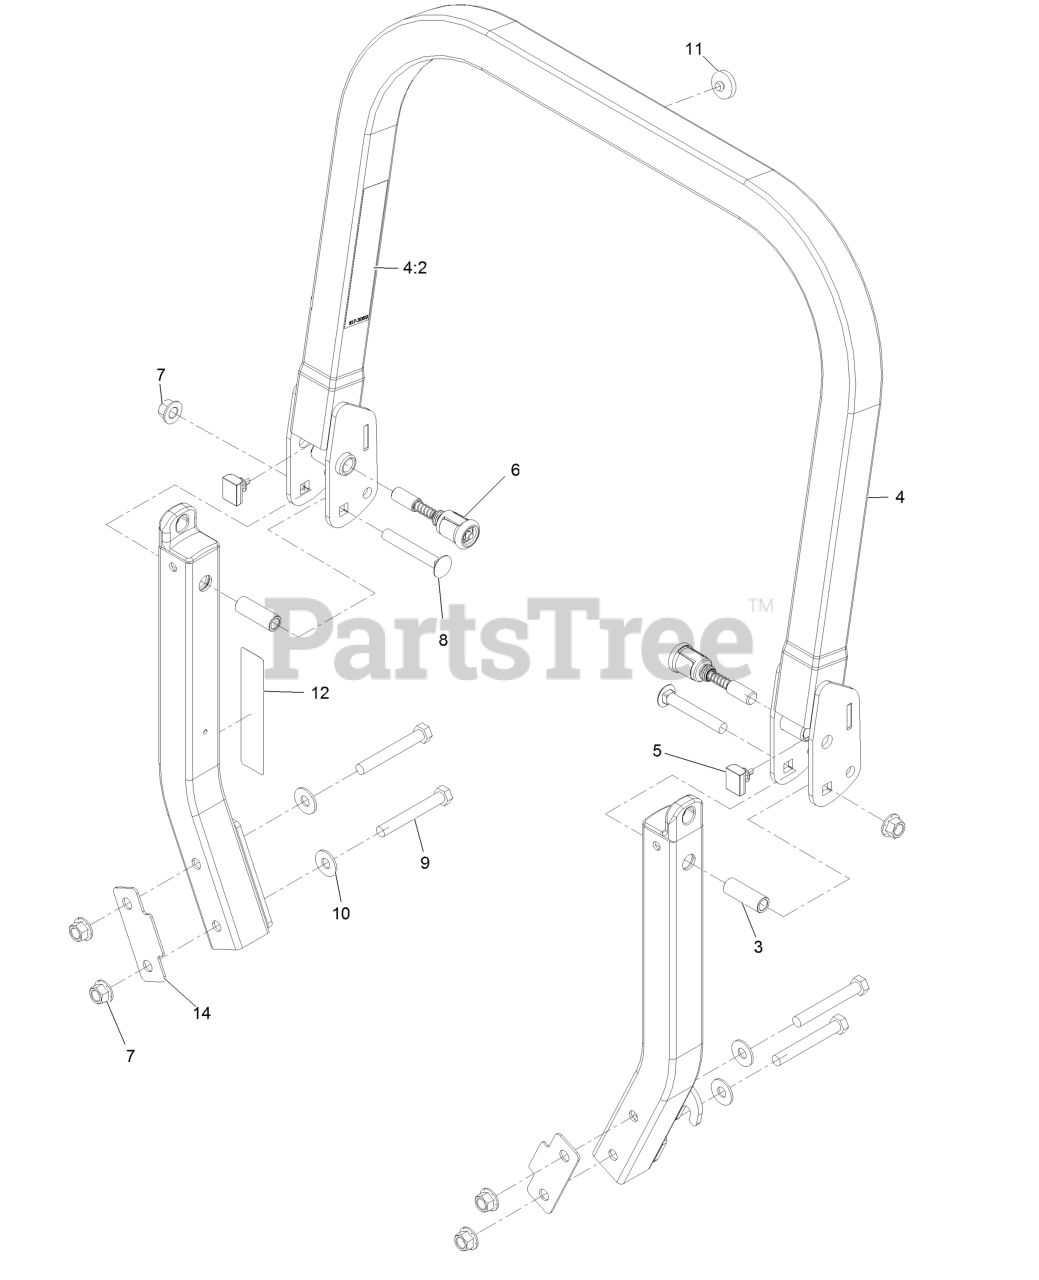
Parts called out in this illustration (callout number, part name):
4	UPPER ROPS ASM
4:2	DECAL-WARNING
5	BUMPER-ROPS
6	PIN-SPRING
7	Nut-Lock 1/2-13
8	SCREW-CARR
9	WASHER-LOCK
10	WASHER-SPRING
11	BUMPER-PUSH-IN, RUBBER
12	DECAL-CAUTION, FUEL VENT
